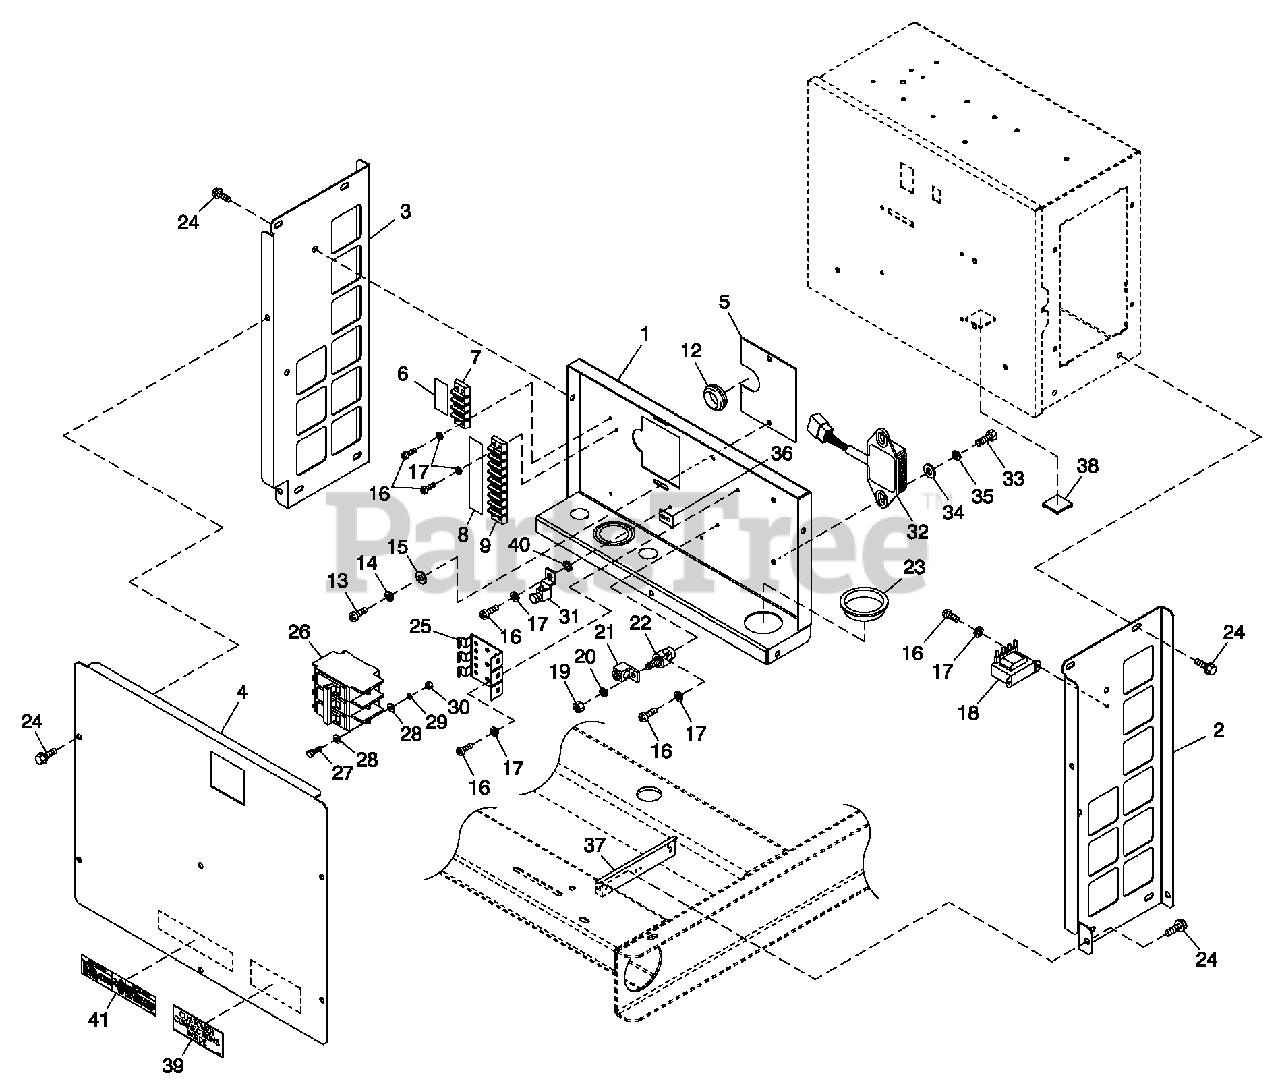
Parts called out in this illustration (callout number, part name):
1	BREAKER TRAY BACK/BOTTOM
2	SUPPORT CONTROL PANEL SIDE RH
3	SUPPORT CONTROL PANEL SIDE LH
4	COVER CIRCUIT BREAKER 2P
5	PLATE WIRE SNGL GALV
6	DECAL CUST CONN 120V UTILITY
7	BLOCK TERM 20A 6 X 3 X 1100V
8	DECAL UTIL SENSE/CUST CONN
9	BLOCK TERM 20A 8 X 6 X 1100V
12	GROMMET 1.25 X .25 X .75
13	SCREW HHTT M5-0.8 X 12 BP
14	WASHER LOCK M5
15	WASHER FLAT M5
16	SCREW PHTT M4-0.7 X 16 ZYC
17	WASHER LOCK #8-M4
18	XFMR DUAL 104V/16V (3 PHASE)
19	NUT HEX 3/8-16 STEEL
20	WASHER LOCK 3/8
21	LUG SLDLSS 350-#6 X 13/32 AL/CU
22	JUNCTION BLOCK 3/8-16
23	BUSHING SNAP SB-2000-26
24	SCREW HWHTF M6-1.0 X 16
25	BRKT CB MTG BACK 2P
26	CB 0125A 2P 240V S BQ2 LL ( 2 POLE)
31	LUG SLDLSS #6-14 X 13/64 CU
32	REGULATOR - DC ALT
33	SCREW HWHTF M6-1.0 X 16
34	WASHER FLAT 1/4-M6 ZINC
35	WASHER LOCK M6-1/4
36	DECAL GROUND LUG
37	BRACKET PANEL SUPPORT 1.5L C1
38	CABLE TIE MOUNT BLACK
39	DECAL CUSTOMER CONNECT INSIDE
40	WASHER SHAKEPROOF EXT #10 STL
41	DECAL DANGER HIGH VOLTAGE BI
